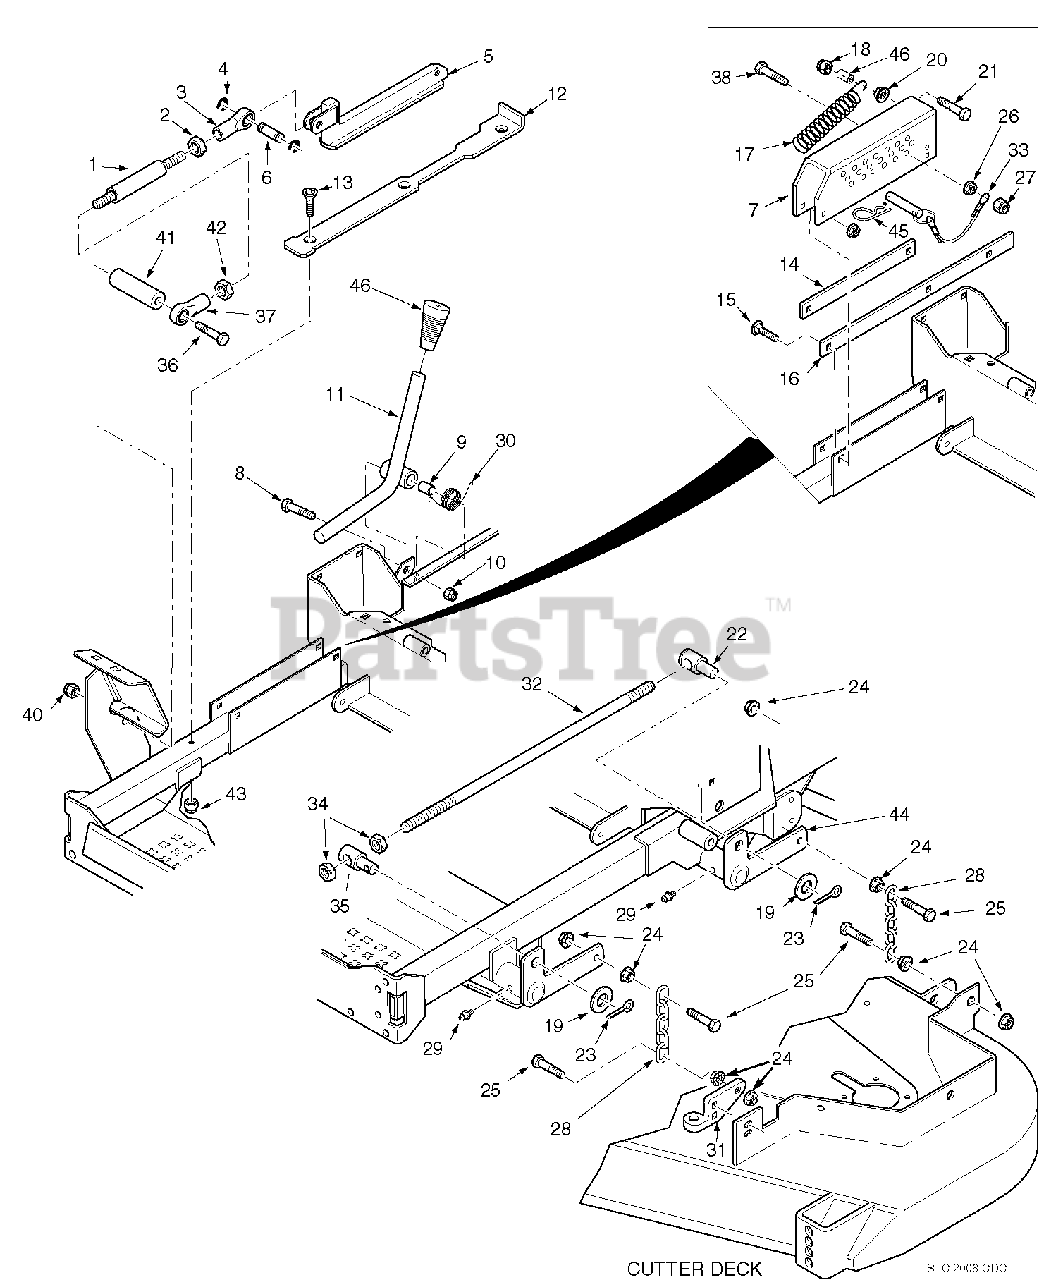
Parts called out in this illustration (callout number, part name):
1	Rod, Deck Lift Linkage
2	Nut, Jam 1/2-20 LH Thread
3	Rod End, 1/2-20 Female Thread
4	Retaining Ring, 1/2" External “E"
5	Slide, Deck Height Adjust
6	Pin, Deck Lift
7	Bracket, Cutting Height Adjustment
8	Bolt, Hex Head 3/8-16 x 2-3/4"
9	Bushing .502" OD
10	Nut, Elastic Stop 3/8-16
11	Lever, Deck Latch
12	Slide, Cutting Height
13	Screw, Cap 5/16-18 x 3" FHHS
14	Guide, Short
15	Bolt, Carriage 5/16-18 x 1"
16	Guide, Long
17	Spring, Helper
18	Nut, 3/8-16 Center Lock
19	Flatwasher, 5/8-.656 x 1.312 x .095"
20	Nut, 3/8-16 Serr. Flange
21	Bolt, Hex Head 3/8-16 x 1-1/4"
22	Swivel Joint LH
23	Cotter Pin, 3/16 x 1"
24	Nut, Serr. Flange 3/8-16
25	Bolt, Hex Head 3/8-16 x 1-1/2"
26	Nut, Serr. Flange 3/8-16
27	Nut, Elastic Stop 3/8-16
28	Chain
29	Grease Fitting, 1/4-28 Self Tap
30	Torsion Spring
31	Lever Assy., Deck Level
32	Stud, 1/2-13 x 20"
34	Nut, 5/8-11 UNC
35	Swivel Joint RH
36	Bolt, Hex Head 1/2-13 x 5"
37	Rod End, 1/2-20 Female RH Thread
38	Bolt, Hex Head 3/8-16 x 3-1/2"
39	Spacer
40	Locknut, 1/4-20
41	Spacer
42	Nut, 1/2-20 UNF-2B
43	Nut, Elastic Stop 5/16-18
44	Lift Bellcrank Weldment, LH Rear
45	Hair Pin Cotter, .177 x 3-1/4"
46	Grip, Deck Latch Lever
